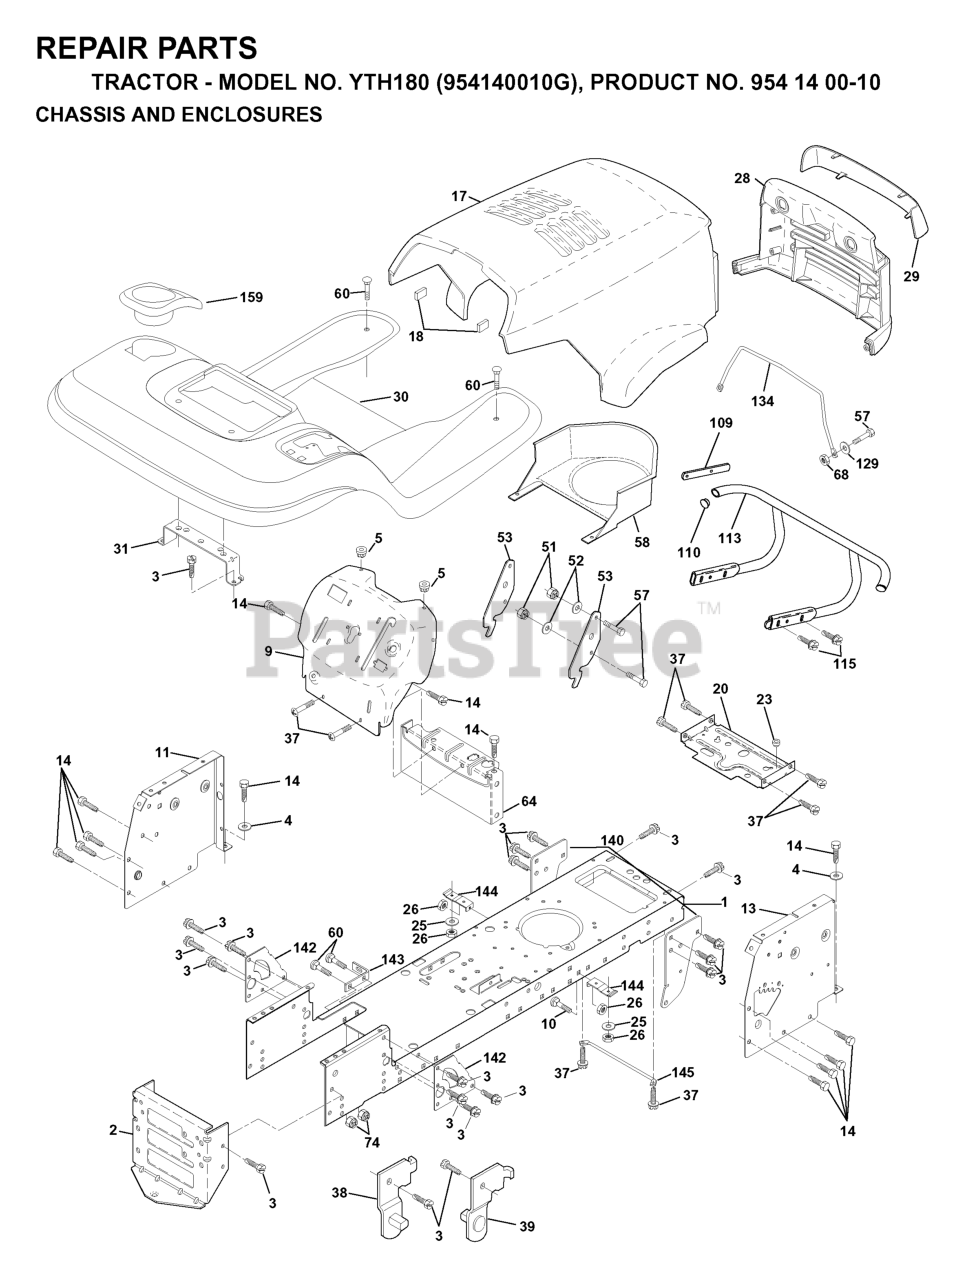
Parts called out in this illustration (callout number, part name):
2	STRETCH DRAWBAR
3	SCREW
4	Washer 13/32 X 3/4 X 16 Ga.
5	BUMPER.RUBBER.HOOD
9	DASH PANEL
10	BOLT D
11	PANEL DASH LH
14	SCREW LT
18	BUMPER HOOD T
20	PLATE MTG
23	BUSHING.SNAP.NYL.BLK.
25	WASHER
26	NUT
28	GRILL
29	LENS
31	BRACKET.SUPPORT.FENDER
37	Screw 5/16-18 x 1/2 Hex, Self Tapping 5/16-18 x 1/2
38	BRACKET LH PIVOT
39	BRACKET RH PIVOT
51	LOCKNUT.NYLOC.1/4-20
52	WASHER
53	BRACKET PNT PICK OFF LT/PL
57	BOLT
60	Bolt - Rd. Hd. Sq. Neckiage 3/8 16 x 3/4
64	DASH LOWER
68	NUT
109	BRACKET BUMPER
110	PLUG PLASTIC
115	SCREW
129	WASHER
134	ROD SUPPORT HOOD LT/PL HUS.
140	BRACKET SUSPENSION FRONT
142	PLATE
143	BRACKET, SWAY BAR
144	BRACKET FOOTREST
145	ROD PIVOT CHASSIS/HOOD
159	CUPHOLDER
